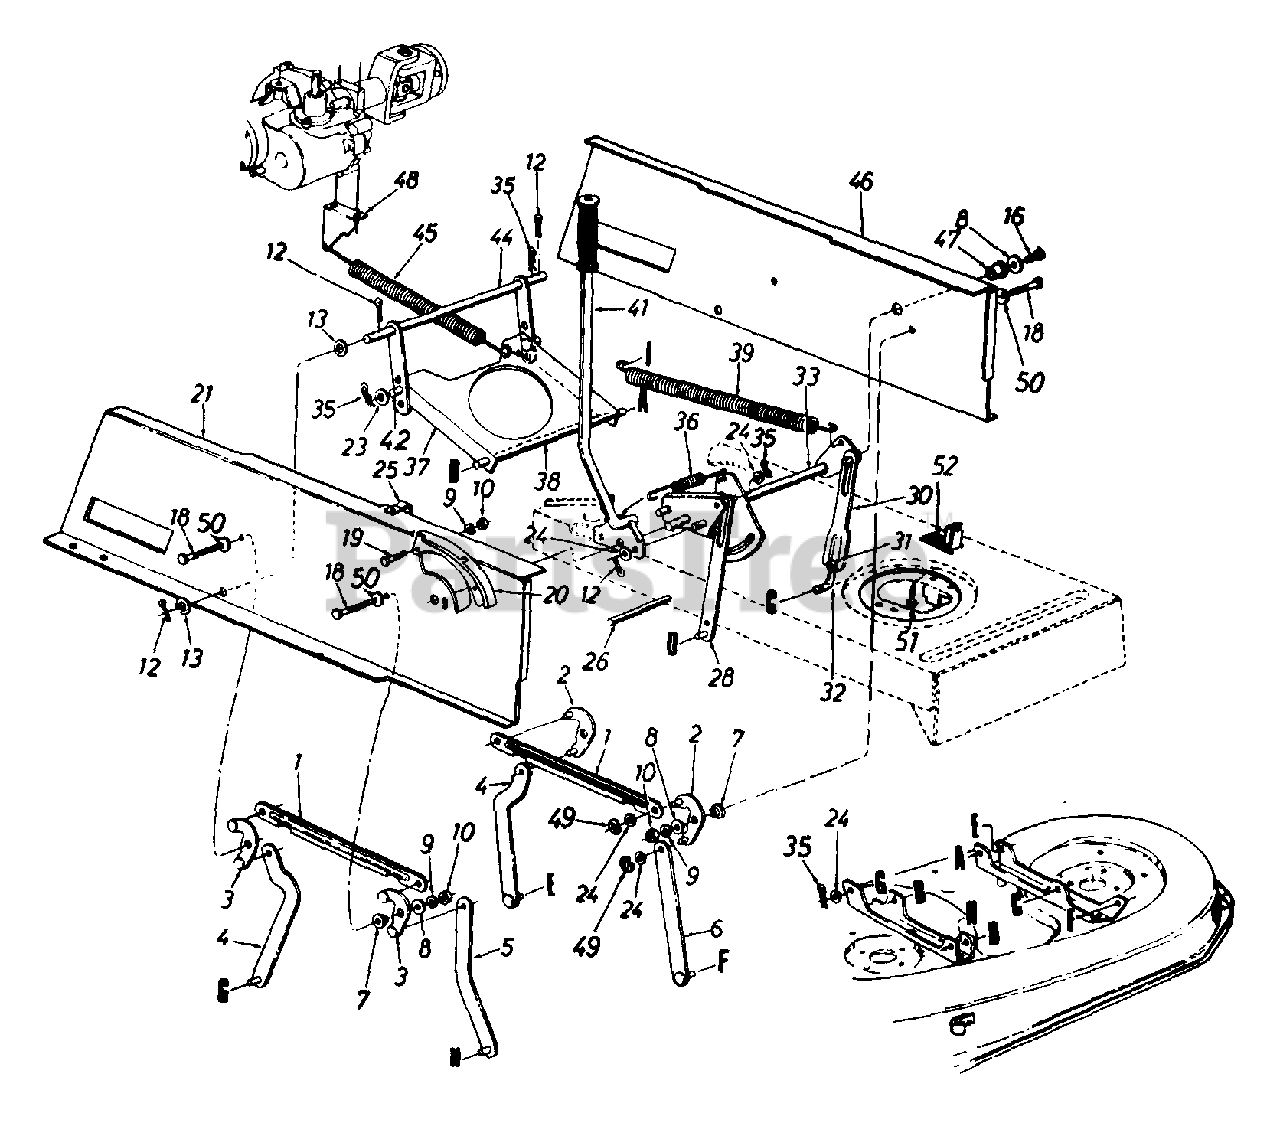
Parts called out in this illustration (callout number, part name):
3	Pivot Link Ass'y. - R.H.
7	Shld. Spacer .318" I.D.
8	Fl-Wash. .344" I.D. x .62" O.D.
9	L-Wash. 5/16" I.D.
10	Hex Nut 5/16-18 Thd.
12	Cotter Pin 1/8" Dia.
13	Fl-Wash. .635" I.D. x 1.0" O.D.
16	Hex Wash. TT-Tap Scr. 5/16-18 x .75" Lg.
18	Hex Wash. Hd. Scr. 5/16-18 x .875" Lg.
19	Hex Bolt 5/16-18 x .75" Lg.
21	Upper Frame - R.H.
23	Fl-Wash. .385" I.D. x .87" O.D.
24	Fl-Wash. .531" I.D. x .93" O.D.
26	Running Board Rod
31	Hex Nut 1/2-20 Thd. (Gr. 5)
32	Lift Link Adjuster
33	Lift Shaft Ass'y.
35	Inter. Cotter Pin 3/8" Dia.
36	Extension Spring
39	Extension Spring
46	Upper Frame - L.H.
47	Flange Brg. .632" I.D.
49	"E"-Ring
50	Bell-Wash. .325" I.D.
51	Hex Wash. Hd. TT-Tap Scr. 1/4-20 x .5" Lg.
52	Spring Switch
